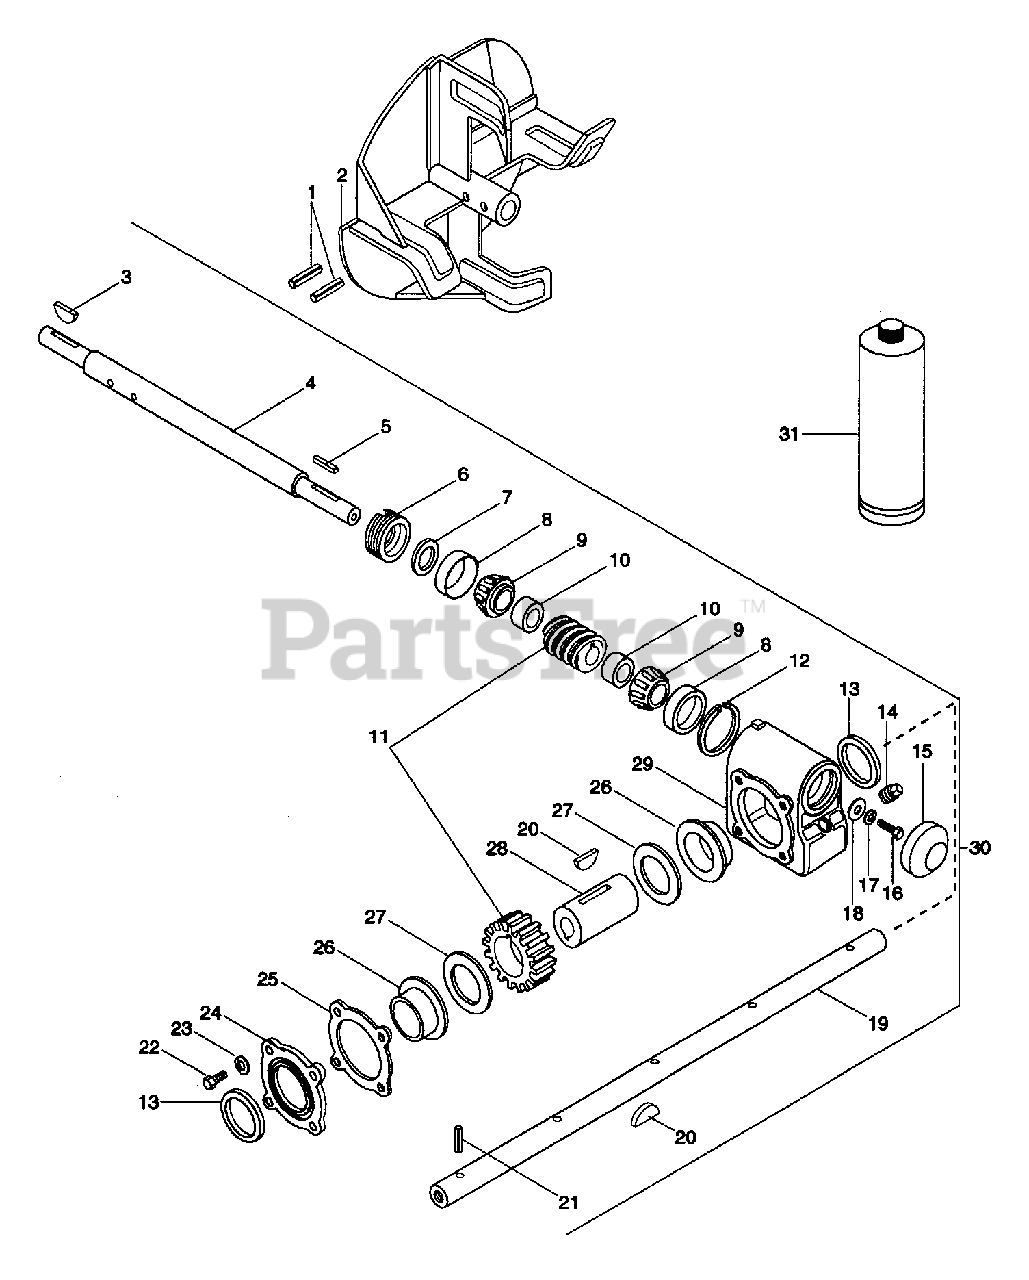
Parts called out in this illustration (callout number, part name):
1	PIN-ROLL .313X1.75
2	FAN - 14"
3	KEY-WDRF .188X.875X.375 SAE11
4	SHAFT, WORM - 1.00 DIA.
5	KEY-SQ .188X1.0X.188 SAE 8630
6	ADJUSTMENT PLUG - 1" SHAFT
7	SEAL 1.000X1.312X.150
8	BRG-CUP 1.781X.475
9	BRG-CONE .750X.61
10	BSHG, SPCR .755X1.12X.50 PM
11	WORM & GEAR SERVICE ASSEMBLY
12	RG-RTNG-INT 1.781X.062
13	SEAL 1.625X2.125X.250
14	PIPE PLUG
15	DUST CAP
16	BLT-HEX .31-18X.75 PL GR2
17	WSHR-LK .312X.097 PL HVY
18	WSHR-FL-STL .328X1.0X.094
19	SHAFT, 32" RAKE - 1.00 DIA.
19	SHAFT, 28" RAKE - 1.00 DIA.
19	SHAFT, 36" RAKE - 1.00 DIA.
20	KEY-WDRF .25X.875X.375 SAE A
21	PIN-ROLL .188X1.50
22	BLT-HEX .25-20X.75 PL GR2
23	WSHR-LK-EXT. 250 ID
24	GEAR CASE COVER
26	BSHG-FLG .683X1.87X1.68X2.250
27	WSHR-FL-STL 1.625X2.500X.012
28	GEAR CASE SHAFT
29	GEAR CASE - CAST IRON
30	GEAR CASE - CAST IRON
31	ARIENS 16 OZ.BOTTLE OF L2 LUBE
